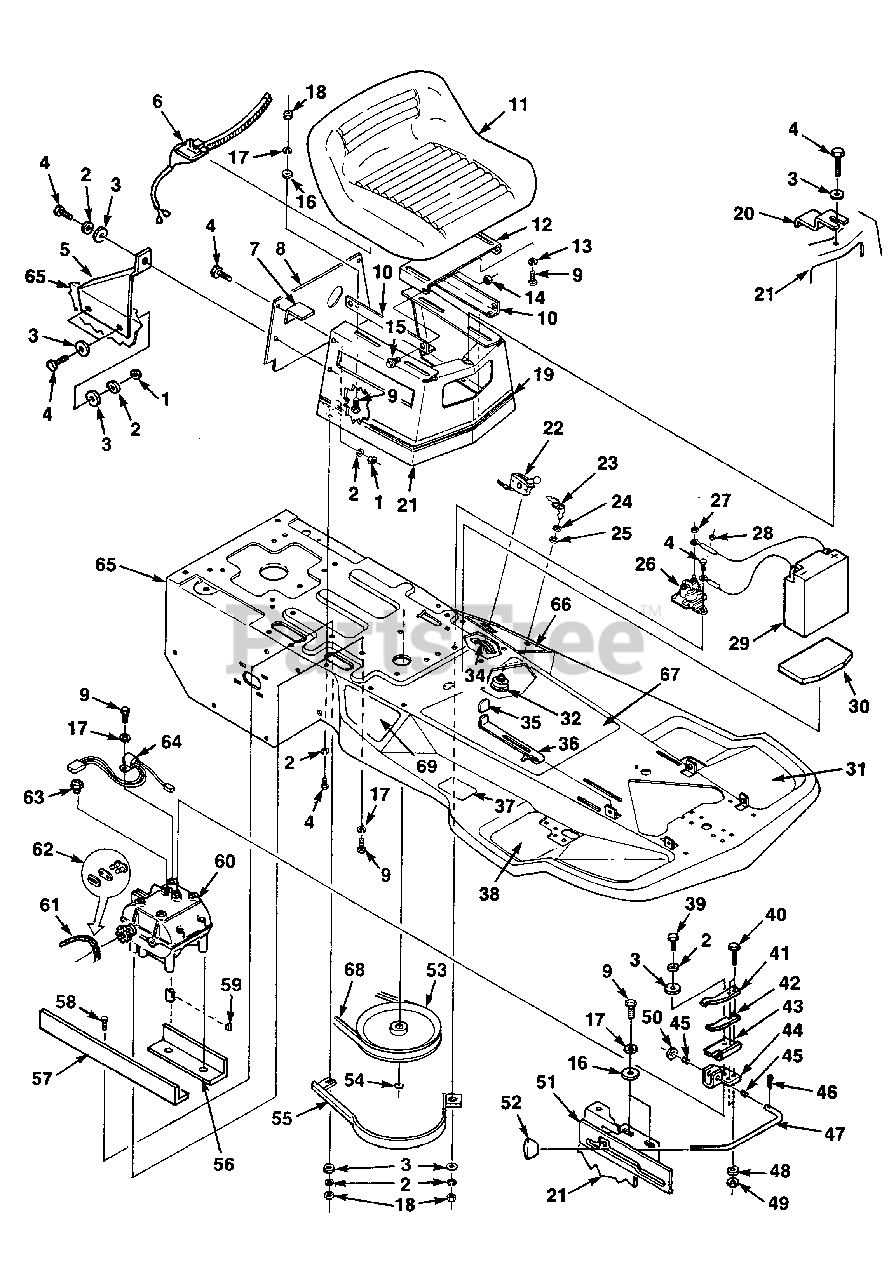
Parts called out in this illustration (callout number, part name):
1	NUT-Hex 1/4-20
2	WASHER-Lock 1/4
3	WASHER-Flat 1/4
4	BOLT-1/4-20 x.625
5	BRACKET-Chain guard
6	SWITCH-Seat
8	PLATE-Reinforcement
9	BOLT-5/16-18 x.750
10	SEAT RAIL
12	BRACKET-Seat
13	WASHER-Lock 5/16
14	NUT-Centerlock hex 5/16-18
15	BOLT-Shoulder 5/16-18 hex
16	WASHER-Plain 5/16
17	WASHER-Lock 5/16
18	NUT-5/16-18 hex
19	DECAL-Seat support
20	BRACKET-Battery
21	SEAT-Tower
22	THROTTLE CONTROL & CABLE
23	KEY-Ignition
24	NUT-Ignition switch
25	WASHER-Ignition switch
26	SOLENOID-Switch
27	NUT
28	NUT
29	BATTERY
30	BATTERY PAD
31	FOOT REST (left hand)
32	IGNITION SWITCH
34	THROTTLE RETAINER
36	LATCHING-Parking brake
38	FOOT REST (right hand)
39	SCREW-Hex hd. 1/4-28 x.750
40	SCREW-Hex hd. sems #10-24 x.625
41	SPRING-Flat (shift yoke)
42	SPRING-Flat (shift yoke)
43	BRACKET-Yoke
44	SHIFT LEVER-Yoke
46	PIN-Cotter 1/8 x 3/4 plated
47	GEARSHIFT LEVER
48	WASHER-Lock #10
49	NUT-Hex 10-24
50	WASHER-Flat 3/8
51	LOCATER-Gear shift
52	KNOB-Shift lever
53	TRANSMISSION PULLEY
54	RING-Snap
55	BELT GUARD-Transmission
56	ANGLE-Short
57	ANGLE-Long
58	BOLT-1/4-20
59	KEY-Transmission
60	TRANSMISSION-Peerless Tecumseh
61	CHAIN-Drive
62	CONNECTING LINK-Chain
63	SWITCH-Neutral safety
64	NEUTRAL START SAFETY INTERLOCK
66	DECAL-Ignition switch
67	DECAL-Instruction
68	BELT-Transmission
69	DECAL-Shift pattern
